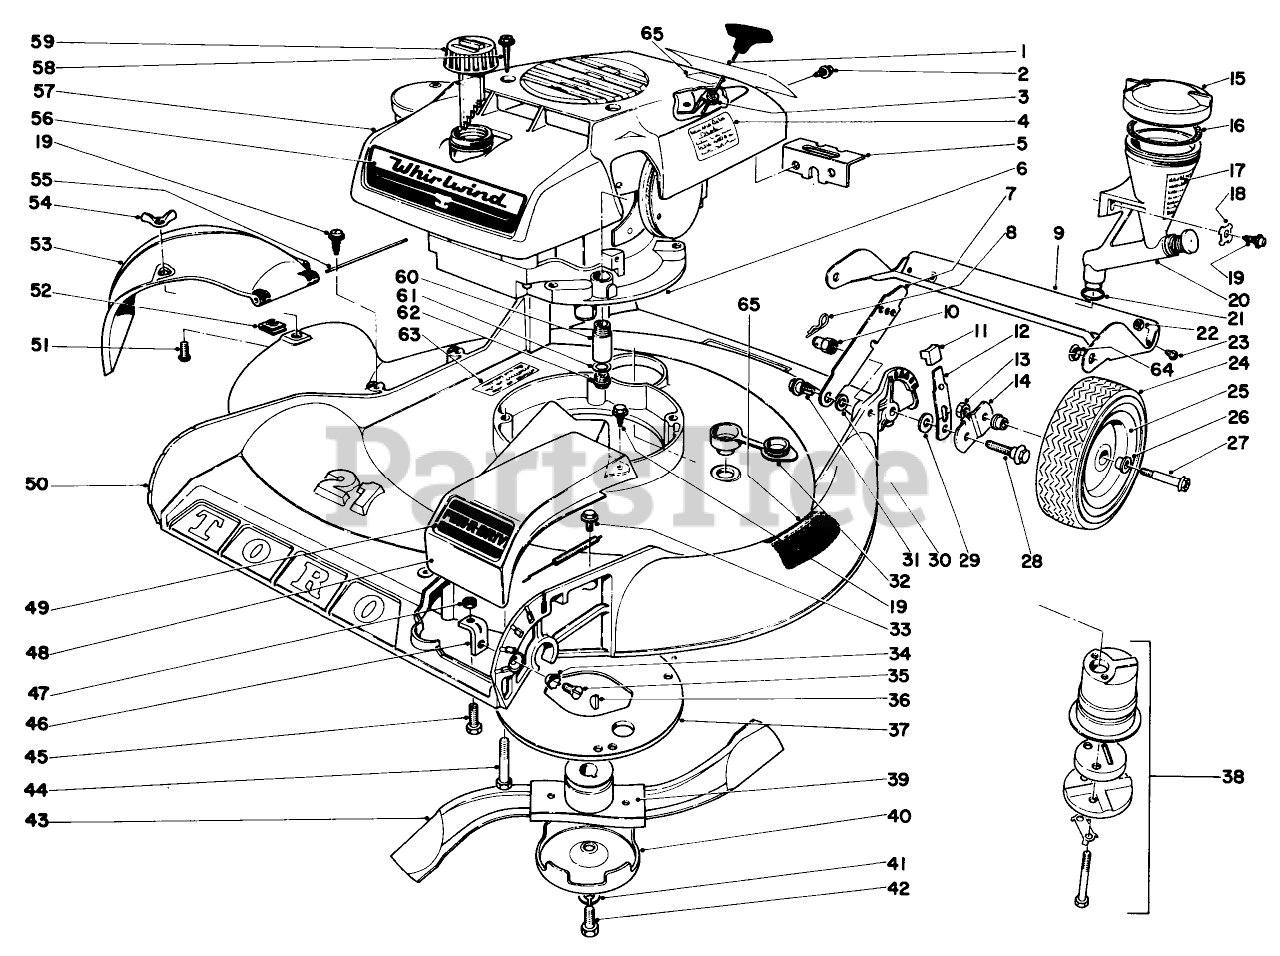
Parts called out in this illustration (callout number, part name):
1	Decal
3	Bracket,Recoil
4	Decal,Start
5	Bracket
6	Engine
8	PIN-COTTER, HAIR
9	Safety Shield-Rear
14	Pivot Arm
15	Cap, Reservoir (Incl. Ref. 15)
17	Decal, Reservoir
18	Washer
21	O-RING
22	NUT-JAM
27	Wheel Bolt
29	WASHER-PIVOT
30	SPACER
31	SCREW-SHOULDER
33	SCREW-HHF
35	Screw, Flat Head
36	KEY-WOODRUFF
39	BLADE RETAINER WA
41	WASHER-LOCK
47	NUT-JAM
48	Guard, Belt
49	Decal
50	Housing
52	NUT-SPEED
54	NUT-WING SPECL
56	Decal
57	Shroud
58	SCREW-HWH
60	Extension Oil Drain
61	Gasket-Oil Drain
62	Plug Oil Drain
64	Nyliner
